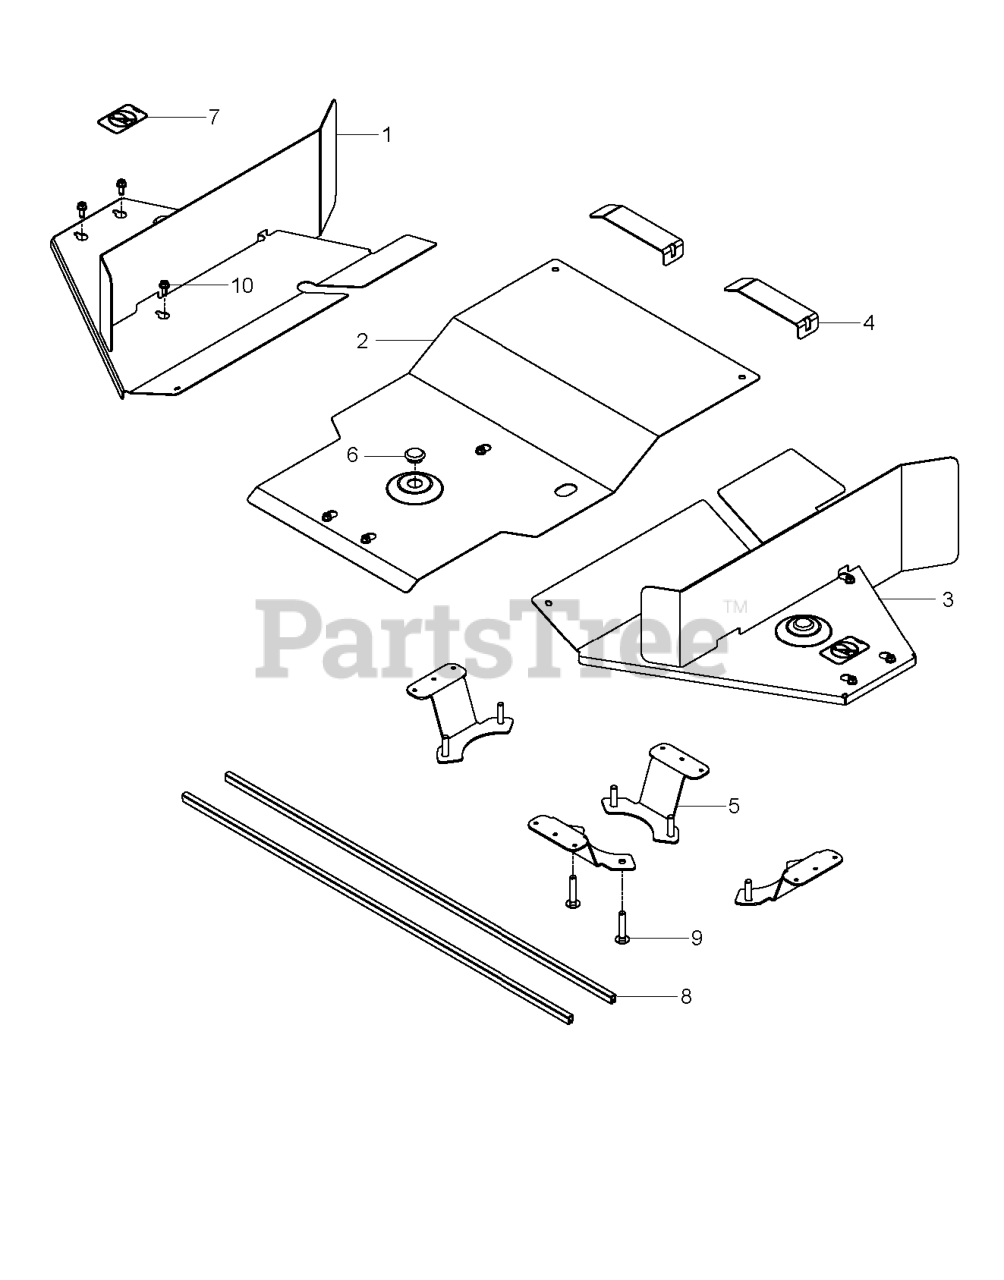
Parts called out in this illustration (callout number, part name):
1	WLDMNT, RIGHT COMBI 61, BLK
2	GUARD.CENTER.COMBI.61.BLACK
3	WLDMNT, LEFT COMBI 61, BLK
4	GUARD, COMBI STRUT, BLK
5	BRACKET,BELT CVR,COMBI BLK
6	PLUG, BUTTON HOLE
7	DECAL, NO STEP
8	RP.FLEX TRIM, BLK-LENGTH 1 FT
9	BOLT, CARRIAGE 5/16X1-1/4
10	SCREW- 1/4-20 X 5/8
